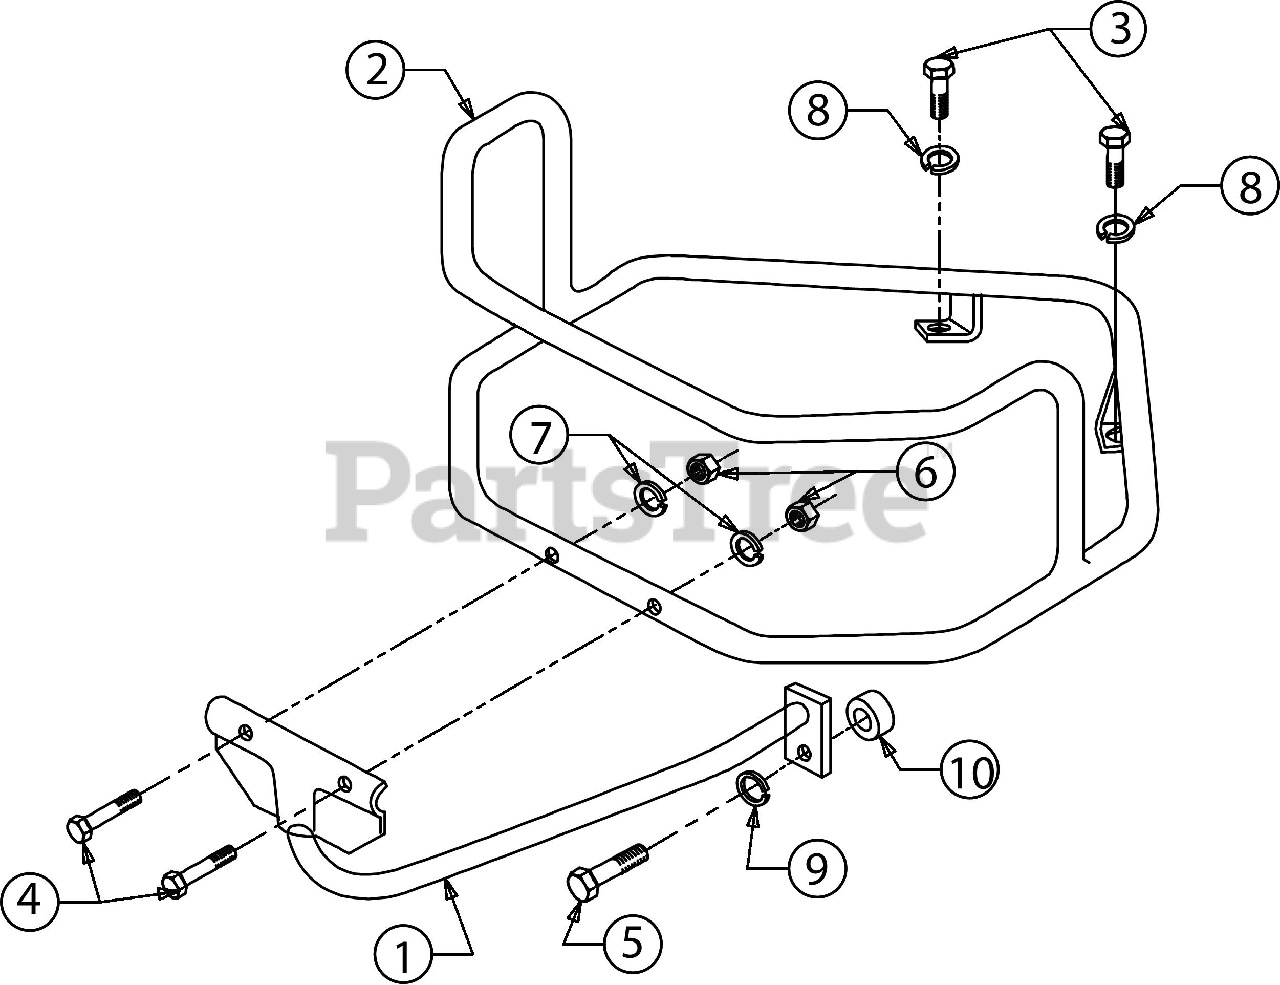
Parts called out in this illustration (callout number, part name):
1	BRACE-BUMPER B
2	GAURD-BUMPER-WRAP
3	SCREW 3/8-16 X GR5
4	SCREW 5/16-18 X 1.50 GR5
5	SCREW 1/2-13 X 1.50 GR5
6	HEX NUT
7	LOCK WASHER 5/16
8	LOCK WASHER 3/8
9	LOCK WASHER 1/2
10	BRACE SPACER
